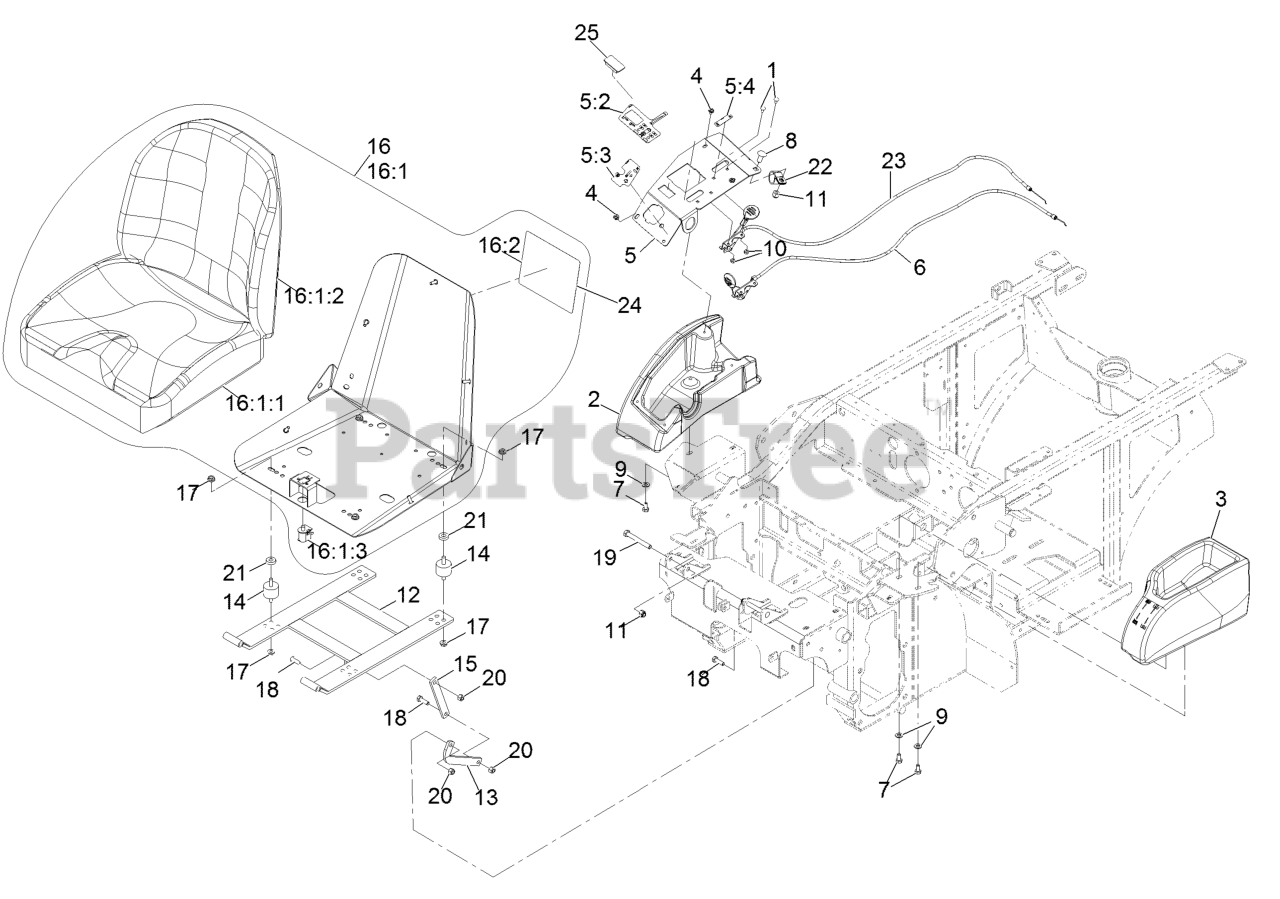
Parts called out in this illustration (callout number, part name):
1	BOLT-CARR
2	CONSOLE-RH
3	CONSOLE, LH GREY
4	SCREW-PPH
5	CONTROL PANEL ASM
5:2	Decal-Nav Console 640Kc
5:3	DECAL-SPEED CONTROL
5:4	DECAL-CHOKE
6	CABLE-THROTTLE
7	SCREW-HH
8	SCREW-CARR
9	WASHER-PLAIN
10	NUT-LOCK, NI
11	NUT-LOCK, NI
12	FRAME-SEAT
13	LINK-SEAT STOP
14	MOUNT-VIBRATION, RUBBER
15	LINK-SEAT
16:1	Seat ASM
16:1:1	ASM-SEAT BOTTOM CUSHION
16:1:2	CUSHION,SEAT BACK
16:1:3	SWITCH-BAIL
16:2	Decal-Service Aid
18	SCREW-HH
19	SCREW-CARR
20	NUT-LOCK, NI
21	SPACER
22	CLIP-LOOM
23	CABLE-CHOKE
24	Decal-Service Aid
25	PLUG-HOLE
